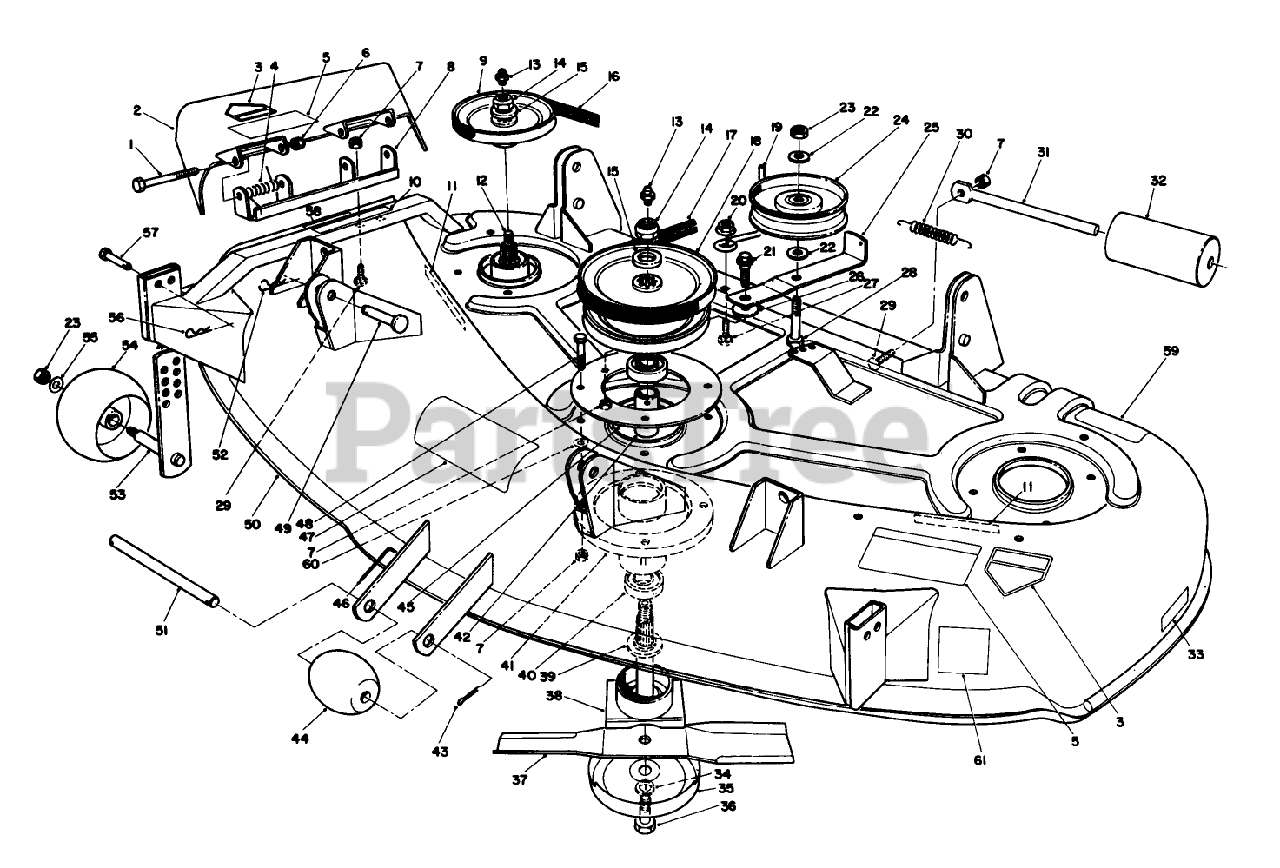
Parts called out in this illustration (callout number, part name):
1	SCREW-HH
3	DECAL-DANGER
4	SPRING
5	DECAL-DANGER, THROWN OBJECT
6	NUT-HEX
7	NUT-LOCK, NI
8	PIVOT BRKT WA
9	PULLEY-DECK
11	DECAL-DANGER
13	FITTING-GREASE
14	NUT-HEX
15	WASHER
16	V-BELT, ENG/DECK
17	V-BELT, DRIVE
18	PULLEY-CENTER
19	ROD-BELT
20	NUT-HF
21	SCREW-SHOULDER
22	WASHER-FLAT
23	NUT-LOCK, NI
24	PULLEY-IDLER
26	WASHER-PIVOT
27	BOLT-CARR
28	SCREW-HH
29	SCREW-CARR
30	SPRING-EXTENSION
31	ROD-ROLLER
32	ROLLER-DECK
34	WASHER-LOCK
35	CUP-SCALP, ANTI
36	SCREW-BLADE
38	SHAFT-SPINDLE
39	SPACER-SPINDLE
40	BEARING-BALL
41	HOUSING-SPINDLE
42	SPACER-BEARING
43	PIN-COTTER
44	ROLLER
46	PIN-SPECIAL
48	SCREW-HH
49	PIN-CLEVIS
50	44" DECK W/DECAL ASM
51	SHAFT-ROLLER
52	PIN-HAIR
53	GAGE-WHEEL
55	WASHER-FLAT
56	PIN-HAIR
57	PIN-CLEVIS
58	DECAL-DANGER
59	DECAL-TORQUE
60	WASHER-FLAT
61	DECAL - WHEEL ADJUSTMENT
